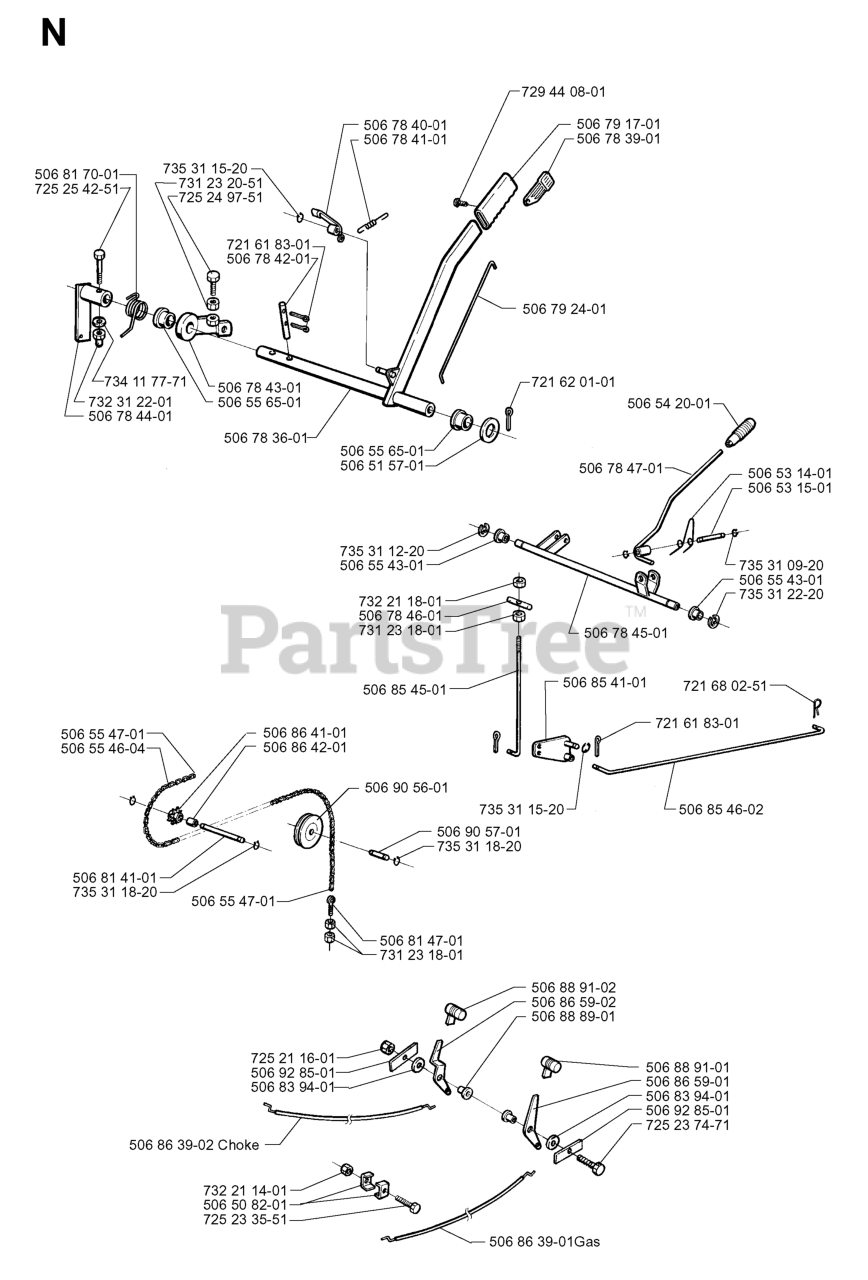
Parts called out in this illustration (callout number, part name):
1	RP WHEEL.STEER.HUSQ.PREM.OVMLD
2	AXLE.CAST.IRON
4	SPINDLE.WELDED.LH.15"TEX
5	SPINDLE.WELDED.RH.15"T
6	THRUST WASHER
9	CAP.SPINDLE.BLACK
14	WASHER, LOCK 3/8
15	NUT CROWNLOCK 3/8-24
16	SHAFT, STEERING
19	PLATE.STEER.DDL.NLT/NG
21	ADAPTER, WHEEL STNG..
22	BUSHING.ASM.STEERING.A
26	RP INSERT.CAP.WHL.STRG.HUSQ.
28	SCREW, 3/8-16X3/4
35	GEAR.SECTOR.PLATE.DDL.
45	WASHER 9/16"ID, 2 3/8"OD
51	NUT.HEX.1/2-20
53	WASHER.HARDENED
57	BRKT.UPSTOP.GT/LT.TEX
58	BOLT.SHOULDER.SECTOR.P
59	WASHER.THURST.SECTOR.S
60	NUT FLANGE LOCK 5/8-11
61	DRAGLINK.LH.BALLSTUD.D
62	DRAGLINK.RH.BALLSTUD.D
63	SCREW
64	RETAINER.CLIP.SPRING.S
66	BOLT HEX FGHD 7/16-14 X 3 SERR
67	BUSHING.PM.FRONT AXLE
68	NUT.LOCK.FLANGE.7/16
69	WASHER.1.5X.505X.118
70	BRKT.DECK.SUSPENSION.F
228	DECAL.WHEEL.STRG.LGN.H
